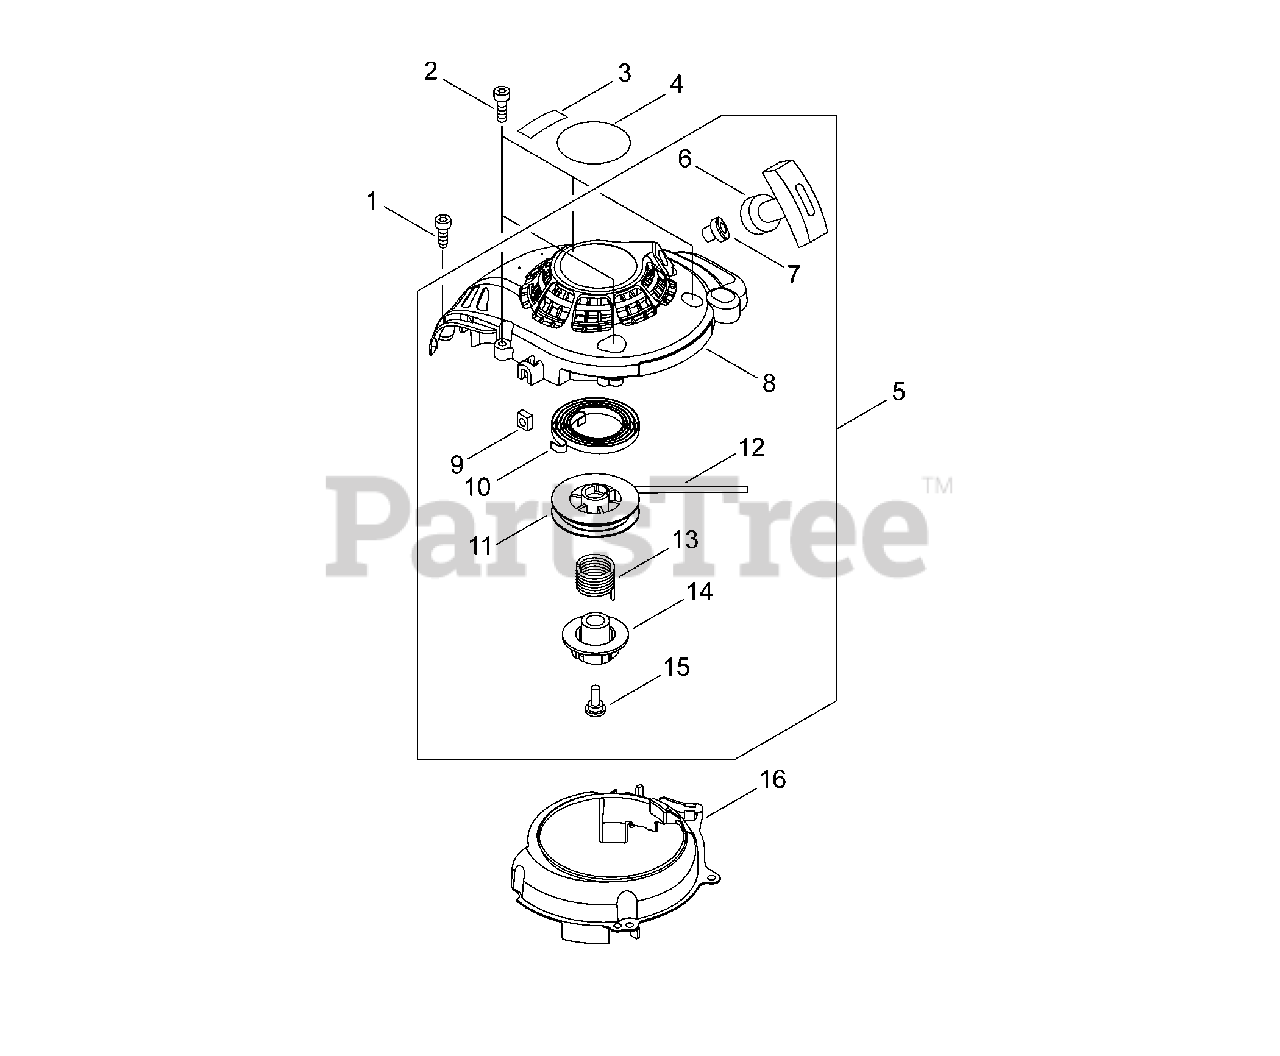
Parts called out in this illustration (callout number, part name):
1	BOLT, TORX 4
2	BOLT, TORX 4
3	LABEL, MODEL
4	LABEL,ECHO
5	STARTER ASY
6	GRIP, STARTER
7	GUIDE, ROPE
8	CASE, STARTER
9	NUT
10	SPRING, REWIND
11	DRUM, STARTER
13	SPRING,DAMPER
14	PLATE, CAM
15	SCREW
16	COVER,FAN
